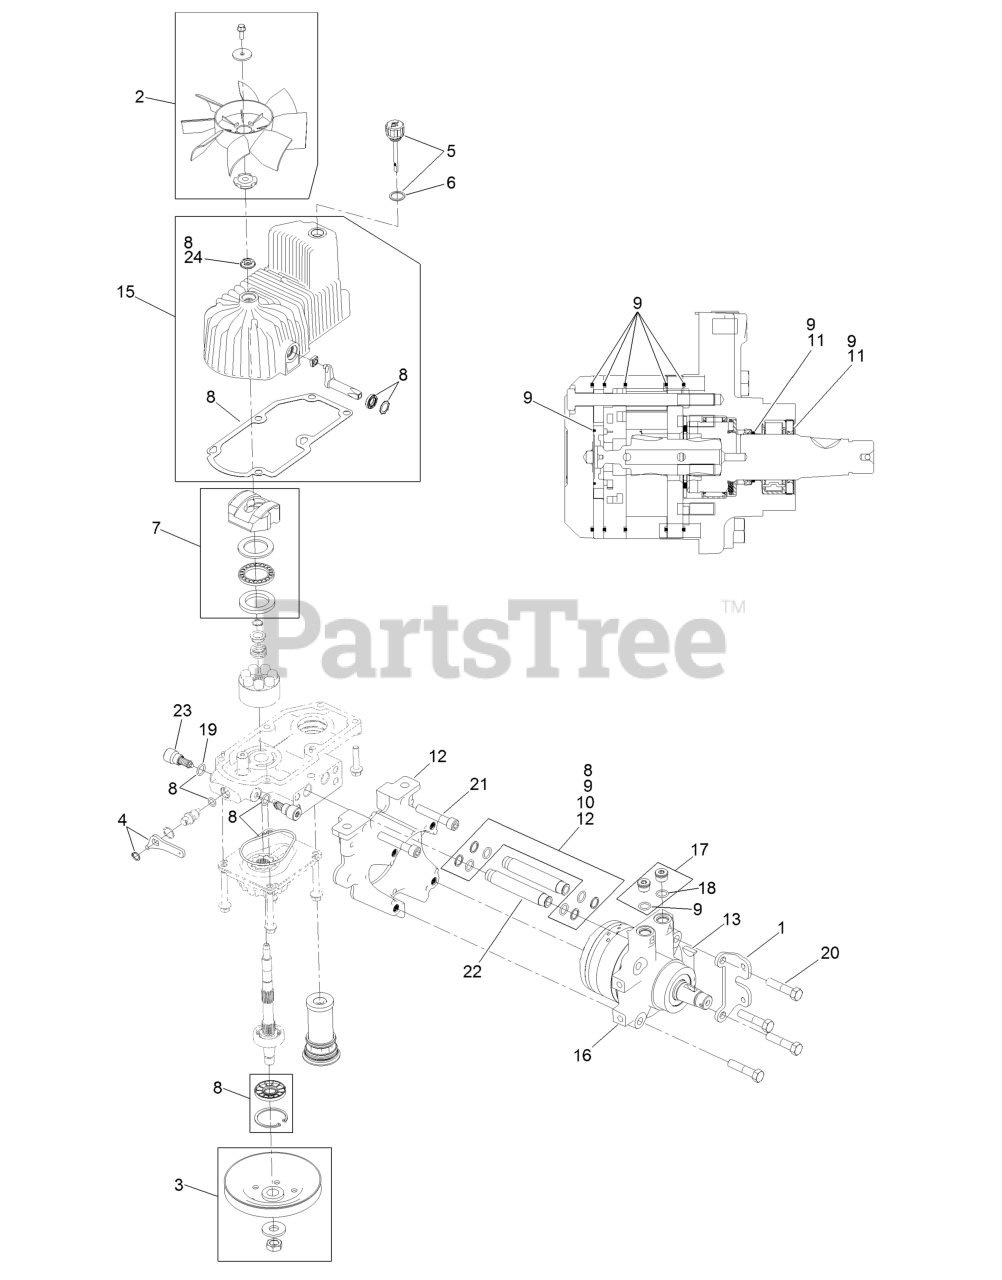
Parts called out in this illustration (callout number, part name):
1	Mount-Shoe, Horse
2	Fan Kit
3	Pulley Kit
4	Handle-Bypass Valve, Hydro
5	Dipstick-Hydro W/Gasket
6	Gasket-Dipstick, Hydro
7	Swash Block Kit
8	Pump Seal Kit
9	Motor Seal Kit
10	Tube Seal Kit
11	Output Shaft Seal Kit
12	Nose Cup-Uht
13	Key-Woodruff
15	Housing-RH
16	Motor-Hydraulic RH 240Cc
17	Magnetic Plugs Service Kit
19	O-Ring-Check Valve
20	Screw HH
21	Screw-HSH
22	Hydraulic Tube Kit
23	Shock Valve, 12Cc Hydro
24	Seal-Fan Drive
99	Puller-Pulley
99	Flow Test Kit
